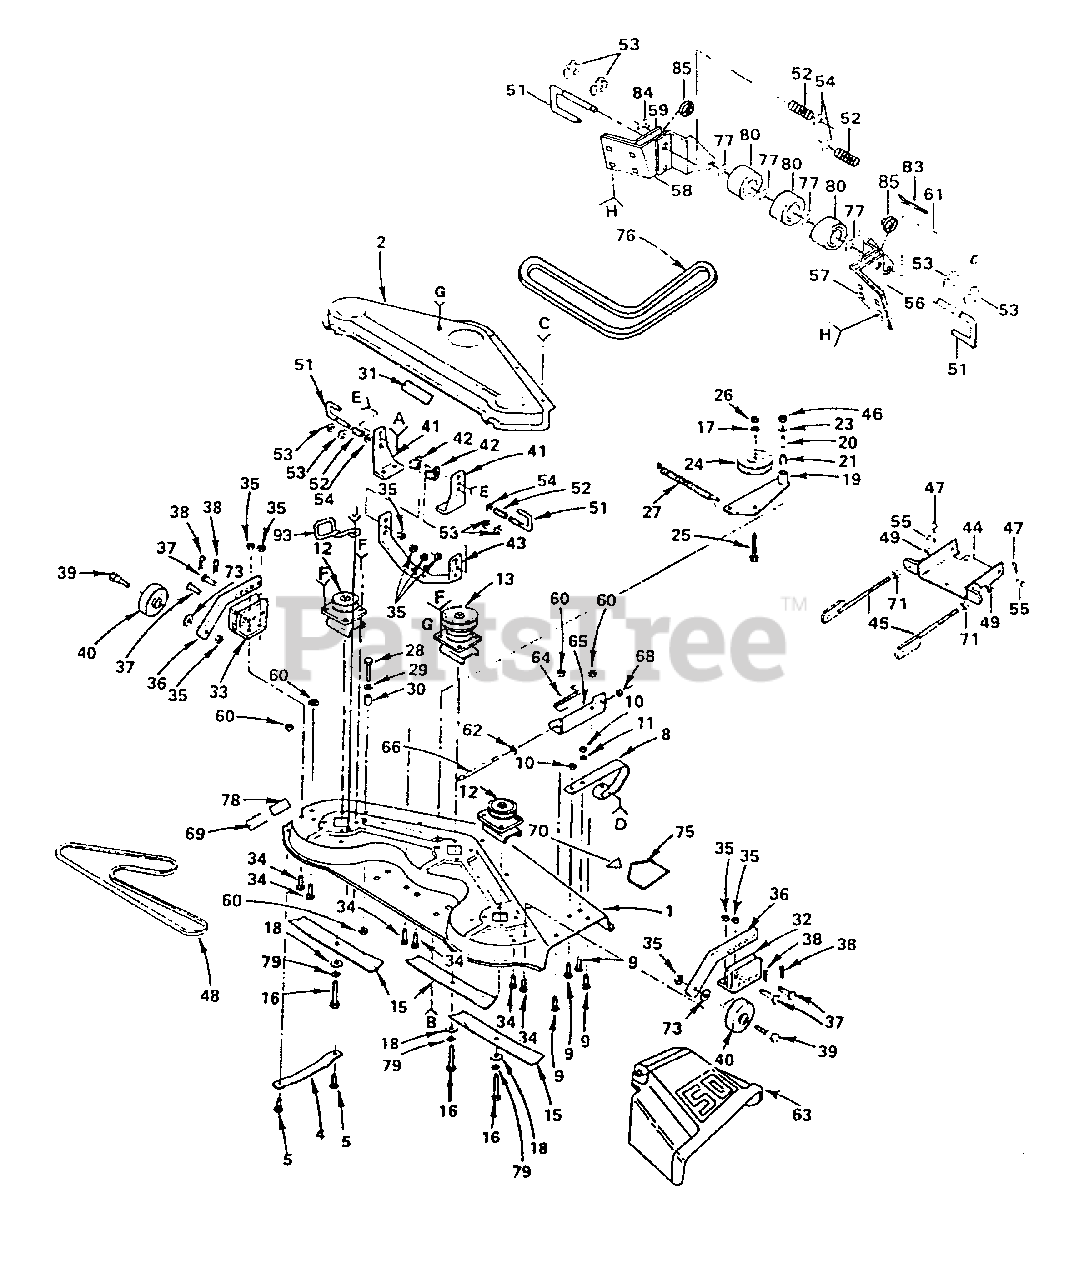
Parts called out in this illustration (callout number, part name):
1	Housing, Mower
2	Cover - Drive, Deck
4	Runner, L.H.
5	Bolt, Carr. 5/16 - 18 x 5/8
8	Runner, R.H.
9	Bolt, Carr. 5/16-18 x 3/4
10	Nut, Lock 5/16- 18
11	Washer 11/32 x 11/16 x 16 Ga.
12	Mandrel - Secondary
13	Mandrel - Primary
16	Bolt- Hex, 3/8 - 24 x 1 - 1/2 Gr. 5
17	Washer- Lock, 3/8
18	Washer 13/32 x 1 - 1/4 x 12 Ga.
19	Arm Assembly, Idler
20	Liner - Bearing
21	Bearing
23	Washer 11/32 x 1-1/8 x 16 Ga.
24	Pulley, Idler
25	Bolt - Hex 3/8 - 16 x 1 -1/2
26	Nut - Hex 3/8- 16
28	Bolt - Hex 5/16-18 x 1 - 1/4 Gr. 5
29	Washer 11/32 x 3/4 x 16 Ga
30	Spacer Split
31	Decal - V-Belt, Dr. Schematic, Mower
32	Bracket, Ga. Wheel, R.H.
33	Bracket, Ga. Wheel, L.H.
34	Bolt, Carriage 3/8 - 16 x 3/4
35	Nut, Crownlock 3/80 16
36	Bar, Ga. Wheel
37	Pin, Clevis
38	Retainer, Spring
39	Bolt, Shoulder
40	Wheel, Gauge
41	Brkt., Suspension
43	Brace, Suspension
44	Plate Assy, Mower Suspension
45	Brkt., Suspension
46	Nut - Hex 5/16 - 18
47	Clip, Hairpin
49	Nut, Crownlock 1/2 - 13
51	Pin, Release
53	Ring, Klip
54	Washer 17/32 x 1 x 12 Ga.
55	Pin, Clevis
56	Brkt., Outer, R.H.
57	Brkt., Inner, R.H.
58	Brkt., Inner, L.H.
59	Brkt., Outer, L.H.
60	Locknut 5/16 - 18
61	Pin, Pivot
62	Washer 11/32 x 5/8 x 16 Ga.
63	Shield, Deflector
64	Spring, Deflector
65	Bracket, Deflector
66	Rod, Hinge
69	Decal, Instruction, Caution (English)
70	Decal, Safety Standard
71	Nut - Hex 3/8 x 16
73	Washer 17/32 x 15/16 x 12 Ga
75	Decal - Warning
77	Washer 15/32 x 1 x 10 Ga.
78	Decal, Instruction, Caution (French)
79	Washer - Lock 3/8
80	Roller, Nose
83	Pin, Cotter
84	Washer 15/30 x 1 x 16 Ga.
93	Keeper, Belt L.H.
